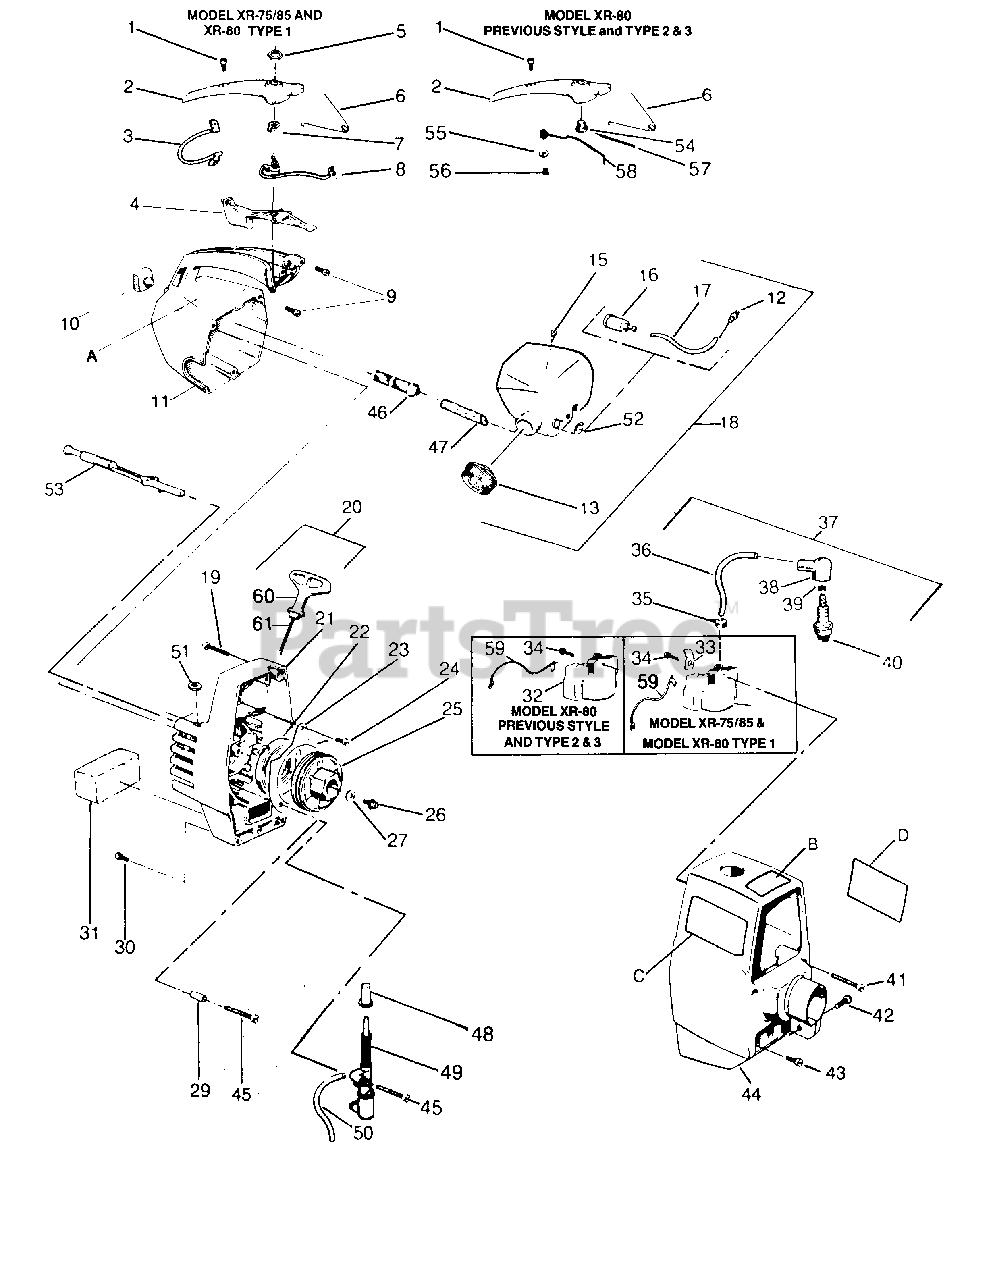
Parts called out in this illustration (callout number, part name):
1	Screw - #8 - 16 x 3/4" Pan Hd. - Handle Cover
2	Handle Cover
2	Model XR-75,XR-85,XR-80 Type 1
2	Model XR-80 Previous Style & Type 2, 3
3	Wire - Lead - Grounding Switch
4	Throttle Trigger
5	Nut - Grounding Switch
6	Spring - Trigger
7	Washer - Grounding Switch
8	Kit - Grounding Switch (Inc. #3, 5, 7 & 33)
9	Screw - #10 - 14 x 3/4" - Fan Hsg. to Handle
10	Bumper - Fuel Tank Hsg.
11	Handle & Fuel Tank Hsg.
12	Fuel Line Fitting
12	Model XR-75; Model XR-80 - Type 2
12	Model XR-80 Type 3
13	Fuel Cap Ass'y (Inc. "O" Ring)
15	Duckbill Valve - Fuel Tank
16	Fuel Pick-up Ass'y.
16	Model XR-75
16	Model XR-85, XR-80 Type 1 & 2
16	Model XR-80 - Type 3
17	Model XR-85, XR-80 Type 1 & Previous Style
17	Model XR-75
17	Line Kit - Model XR-80-Type 2 & 3
18	Fuel Tank Ass'y.
18	Model XR-75, XR-80 - Type 2 & 3
18	Model XR-85, Model XR-80 - Type 1
19	Screw - #10 - 24 x 1-1/2" Fil Hd. - Fan Hsg. Top
19	Model XR-75/85
20	Ass'y - Rope & Starter Handle
21	Kit - Fan Housing
22	Spring Starter Pulley
22	Model XR-80,XR-85
23	Air Baffle
24	Screw - #10 - 24 x 3/8" Fil. Hd. - Air Baffle
24	Model XR-75,XR-85
25	Starter Pulley
25	Model XR-80,XR-85
26	Screw - #10 - 24 x 1/2" - Starter Pulley
26	Model XR-75,XR-85
27	Washer - #10 - Starter Pulley Screw
29	Spacer - Air Baffle - Model XR-75, Model XR-80 Type 2 & 3
30	Screw - #10 - 24 x 5/8" Fil. Hd. - Fan Hsg. Bottom
30	Model XR-75,XR-85
31	Air Filter
32	Kit-Ignition Module
33	Electrical Tab - Model XR-75/85 and XR-80 Type 1
34	Screw - #8 - 32 x 3/4" Fil. Hd.-Ignition Module
35	Grommet - Plug Wire
36	High Tension Lead Wire
37	BEVEL GEAR COMPLETE
38	Boot - Spark Plug
39	Connector - Spark Plug Lead
40	Spark Plug (CJ-14)
41	Screw - #10 - 24 x 1-1/2" - Shroud Top
43	Screw - #10 - 24 x 5/8" Shroud Bottom
45	Model XR-75,XR-85
46	Filter - Fuel (Inlet Line)
47	Line - Fuel Inlet
48	Injector Button
49	Pump Assembly (Inc. #50)
50	Line - Pump to Accumulator
51	Bearing - Nyliner
52	Clip - Retainer - Inlet Line - Fuel Tank
53	Choke Knob
54	Button - Kill Switch
55	Washer - Kill Switch
56	Screw - #8 - 16 x 3/8" Pan Hd. Kill Switch
57	Insulation - Switch Spring Previous Style Only
58	Spring - Kill Switch
59	Lead Wire - Kill Switch - All Models
60	Starter Handle
61	Rope Kit
A	Decal - Starting Instructions
A	Model XR-75
B	Model XR-85
B	Model XR-80 - Previous Style
B	Model XR-80 - Type 1
B	Model XR-80 -Type 2
B	Model XR-80 -Type 3
C	Decal - Shroud (right)
C	Model XR-80 - Type 1, 2
C	Model XR-80 - Type 3
C	Model XR-85
C	Model XR-75
D	Model XR-80 - Type 1, 2
D	Model XR-80 - Type 3
D	Model XR-85
D	Model XR-75
